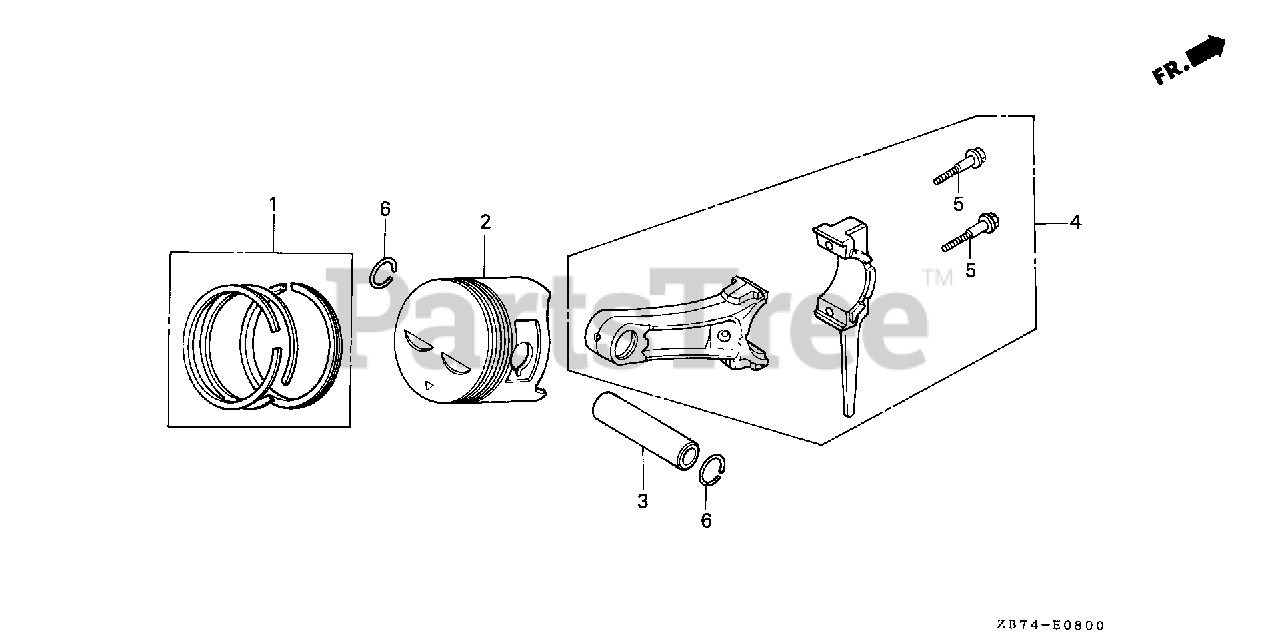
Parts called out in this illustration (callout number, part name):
1	RING SET, PISTON (STD) (TEIKOKU)
1	RING SET, PISTON (OS 0.25) Use from Engine SN 4081305.
1	RING SET, PISTON (OS 0.50) Use from Engine SN 4081305.
1	RING SET, PISTON (STD) (NIPPON)
1	RING SET, PISTON (0.75) Use from Engine SN 4081305.
2	PISTON (STD)
3	PIN, PISTON
4	ROD ASSY., CONNECTING (STD)
5	BOLT, CONNECTING ROD
6	CLIP, PISTON PIN (18MM)
